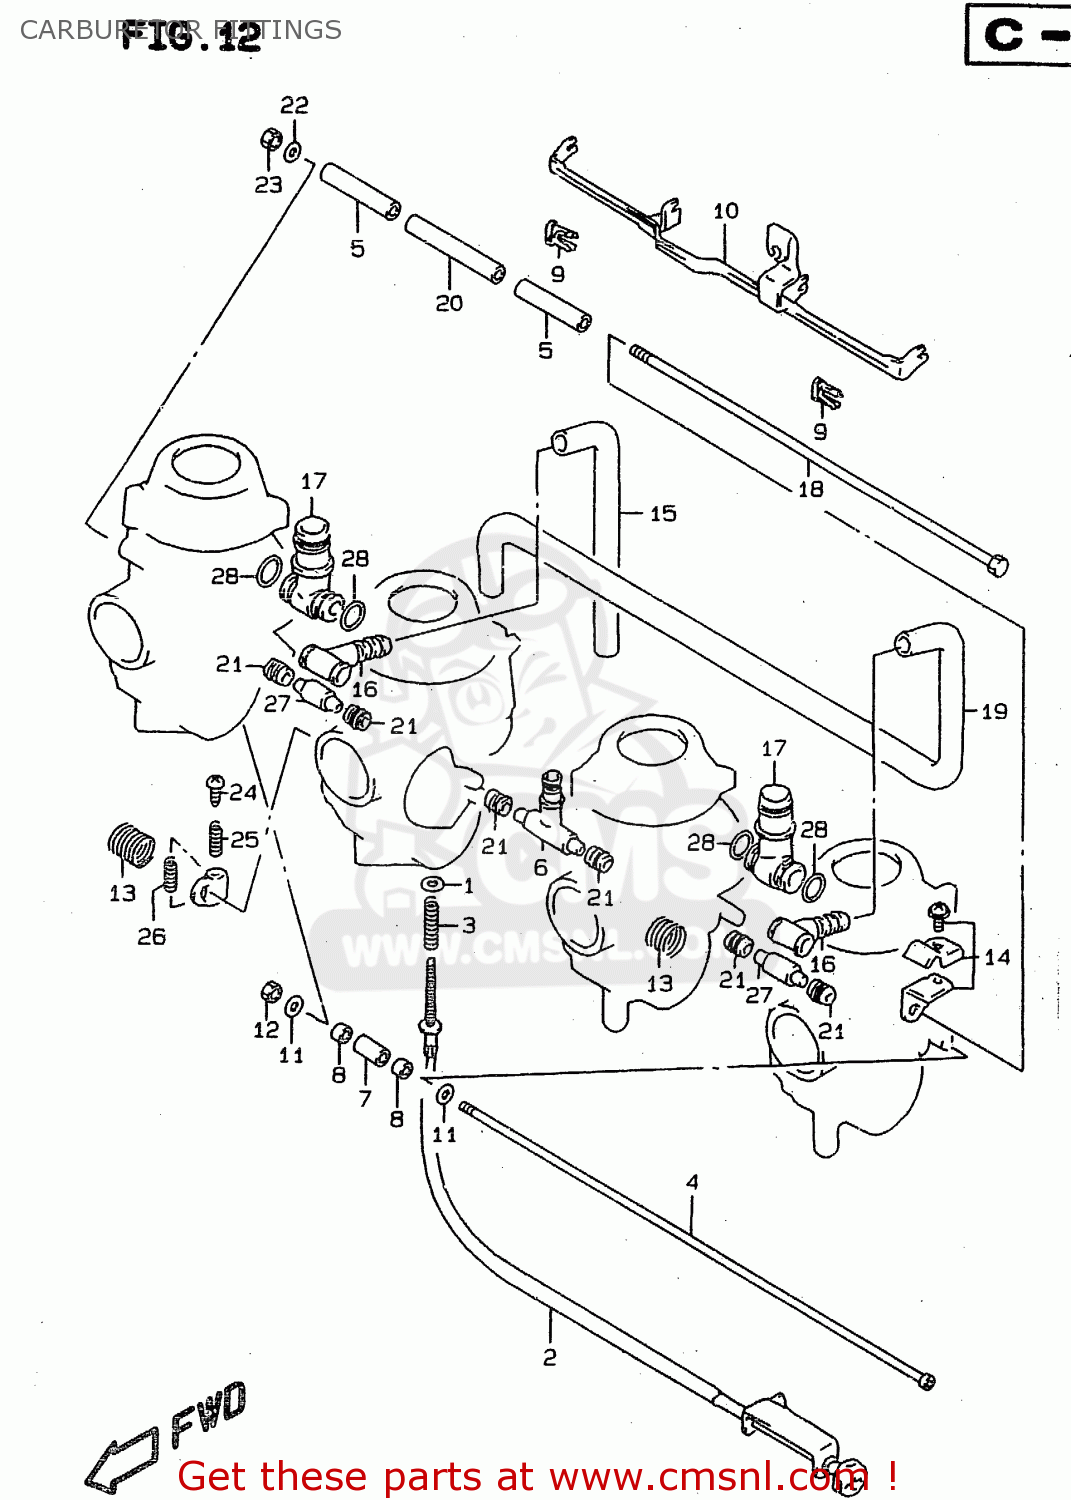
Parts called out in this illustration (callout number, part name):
1	WASHER
2	SCREW,ADJUST
3	SPRING
4	BOLT
5	RING
6	NIPPLE
7	RING
8	RING
9	HOLDER
10	LEVER,STARTER
11	WASHER
12	NUT
13	SPRING
14	BRACKET ASSY
15	HOSE
16	3 WAY
17	NIPPLE
18	BOLT
19	HOSE
20	RING
21	SEAL
22	WASHER
23	NUT 6MM
24	SCREW
25	SPRING
26	SPRING,THROTTLE SCREW
27	PIPE
28	O RING(D:1.9,ID:9.8)
